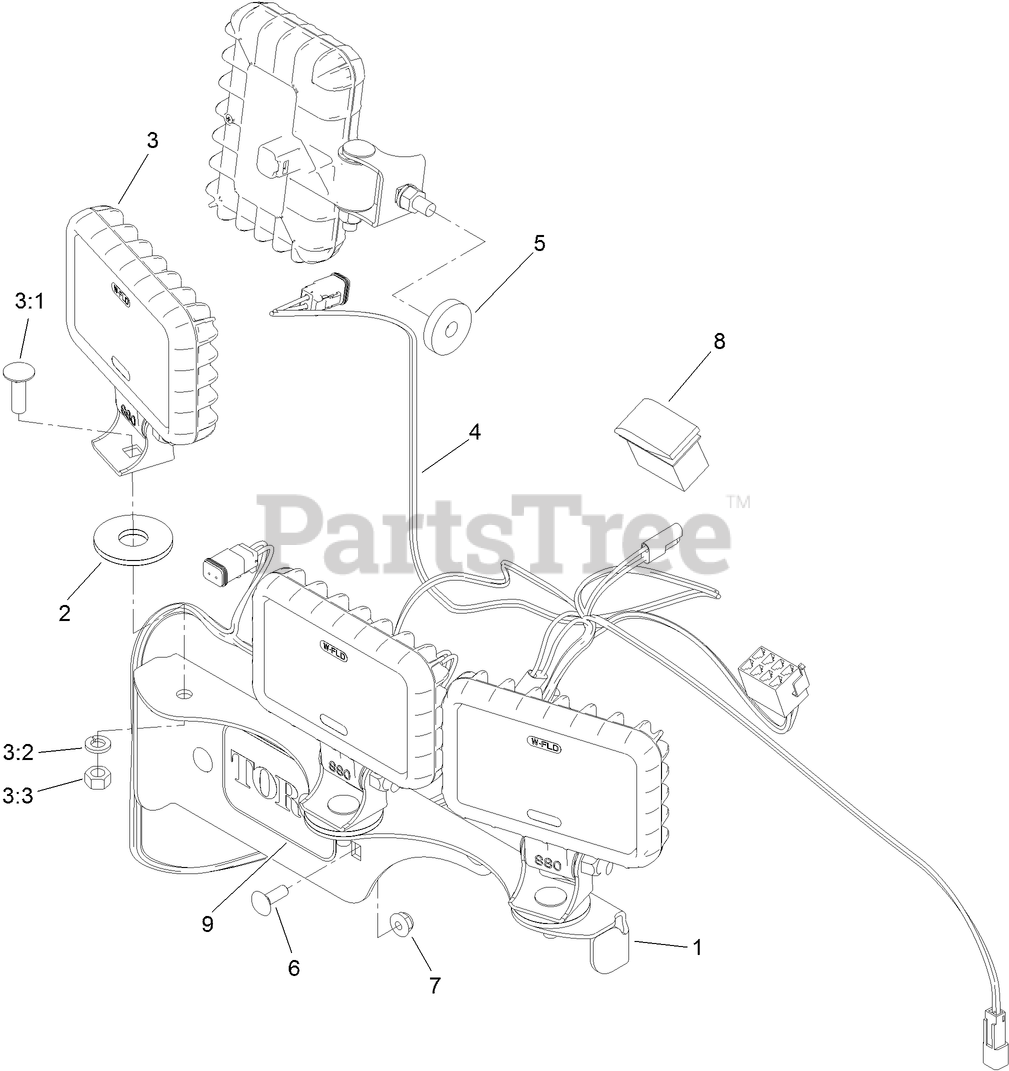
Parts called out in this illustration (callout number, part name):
2	WASHER-FRICTION, COMPOSITE
3	LIGHT-WORK, LED
3:1	SCREW-CARR
3:2	WASHER-LOCK
3:3	NUT-HEX
4	HARNESS-WIRE
5	SPACER-NYLON
6	BOLT-CARR
7	NUT-HF
8	SWITCH-ROCKER
9	DECAL
